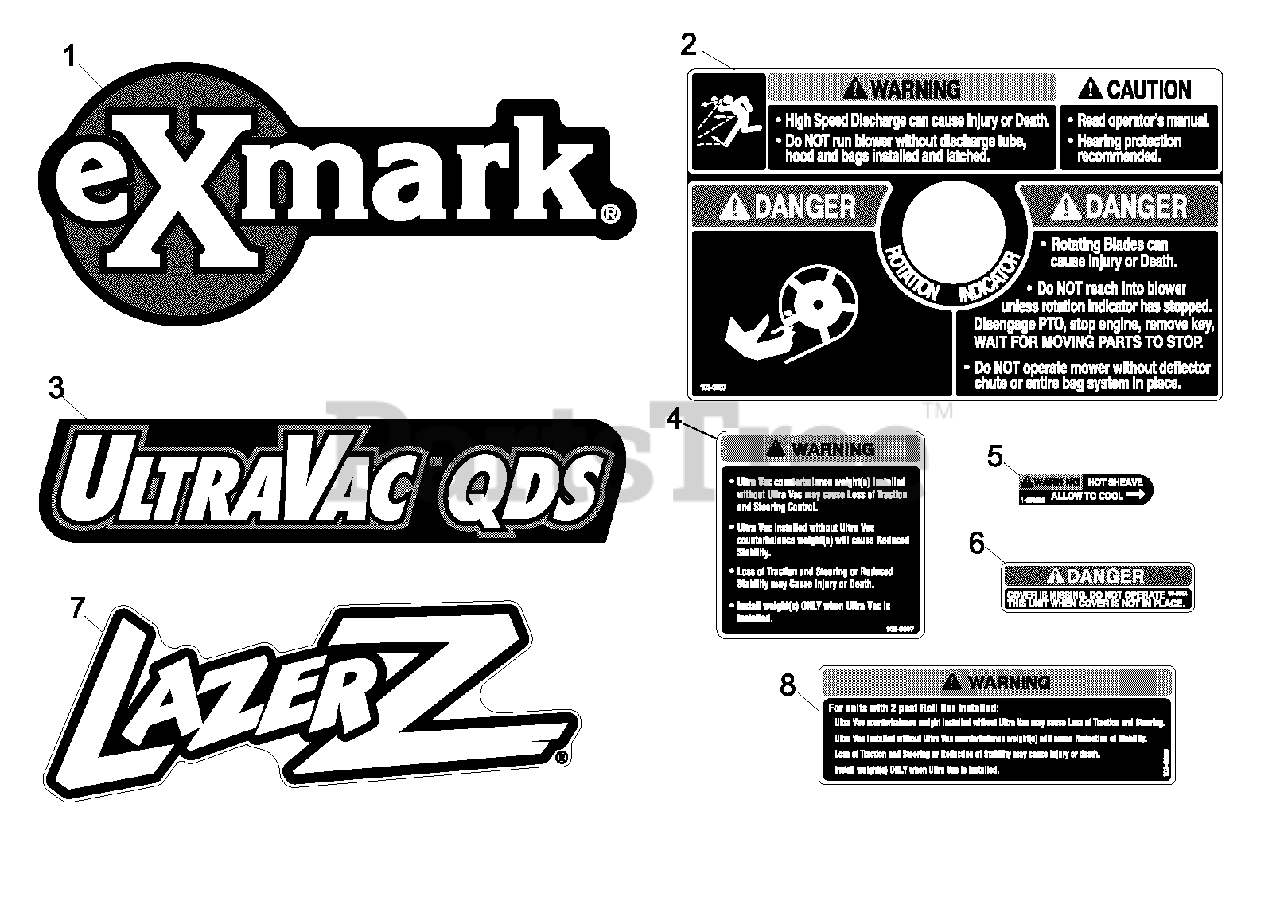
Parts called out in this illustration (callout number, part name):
1	DECAL, EXMARK
3	DECAL, ULTRAVAC QDS
4	DECAL,WEIGHT
5	DECAL-WARNING
6	DECAL-COVER, MISSING
7	DECAL,LAZER MODEL
8	DECAL,WEIGHT
